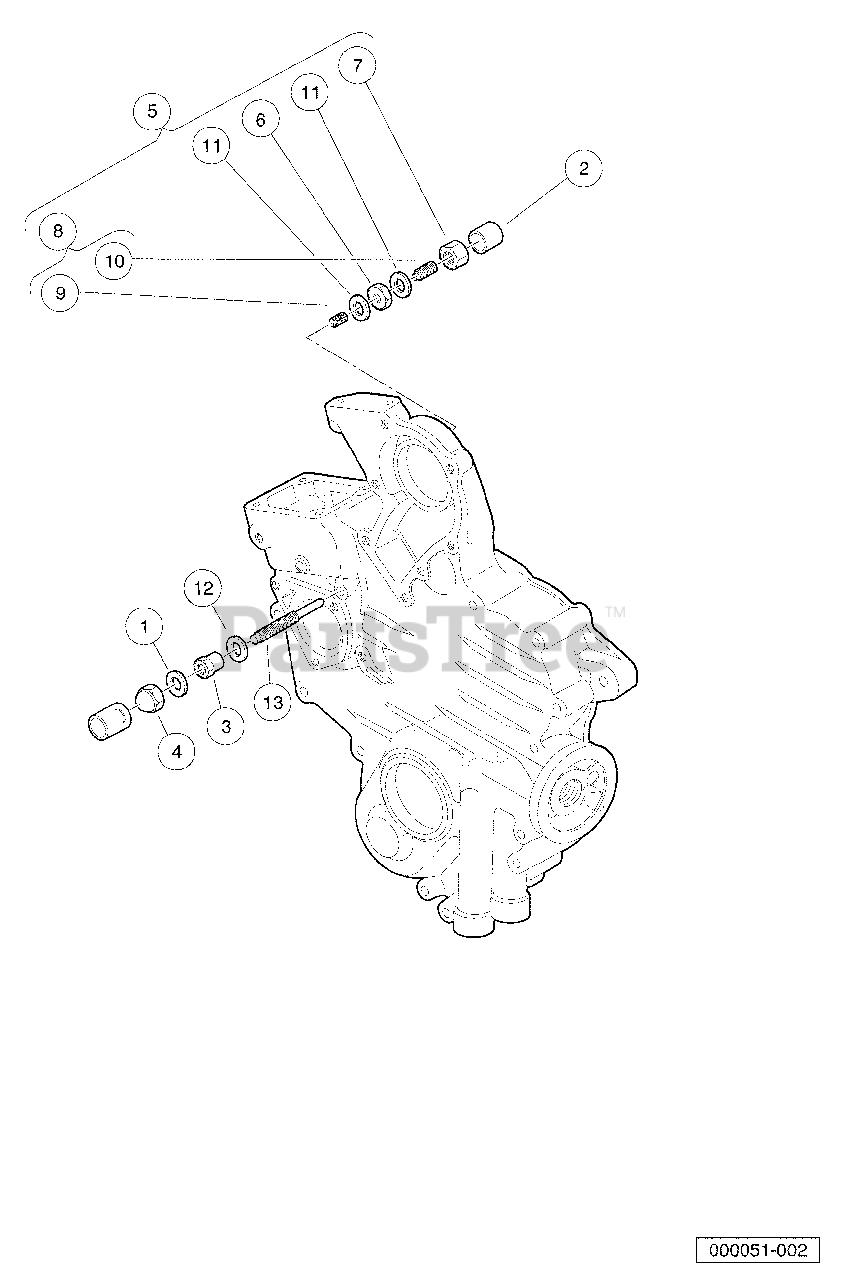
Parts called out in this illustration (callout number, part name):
1	Gasket, 6 X 10
2	Cap, Bolt Assy
3	Nut, Lock, Special
4	Nut, Special
5	Assy, Idle Apparatus
6	Nut, M8, D722 Idle App, Specl
7	Nut, M8, D722 Idle App
8	Assy, Bolt, Adjusting
9	Spring, Idle Apparatus
10	Stud, Idle Adjustment
11	Gasket, Idle Apparatus, Rear
12	Gasket, Idle Apparatus, Front
13	Bolt, Idle Adjusting
